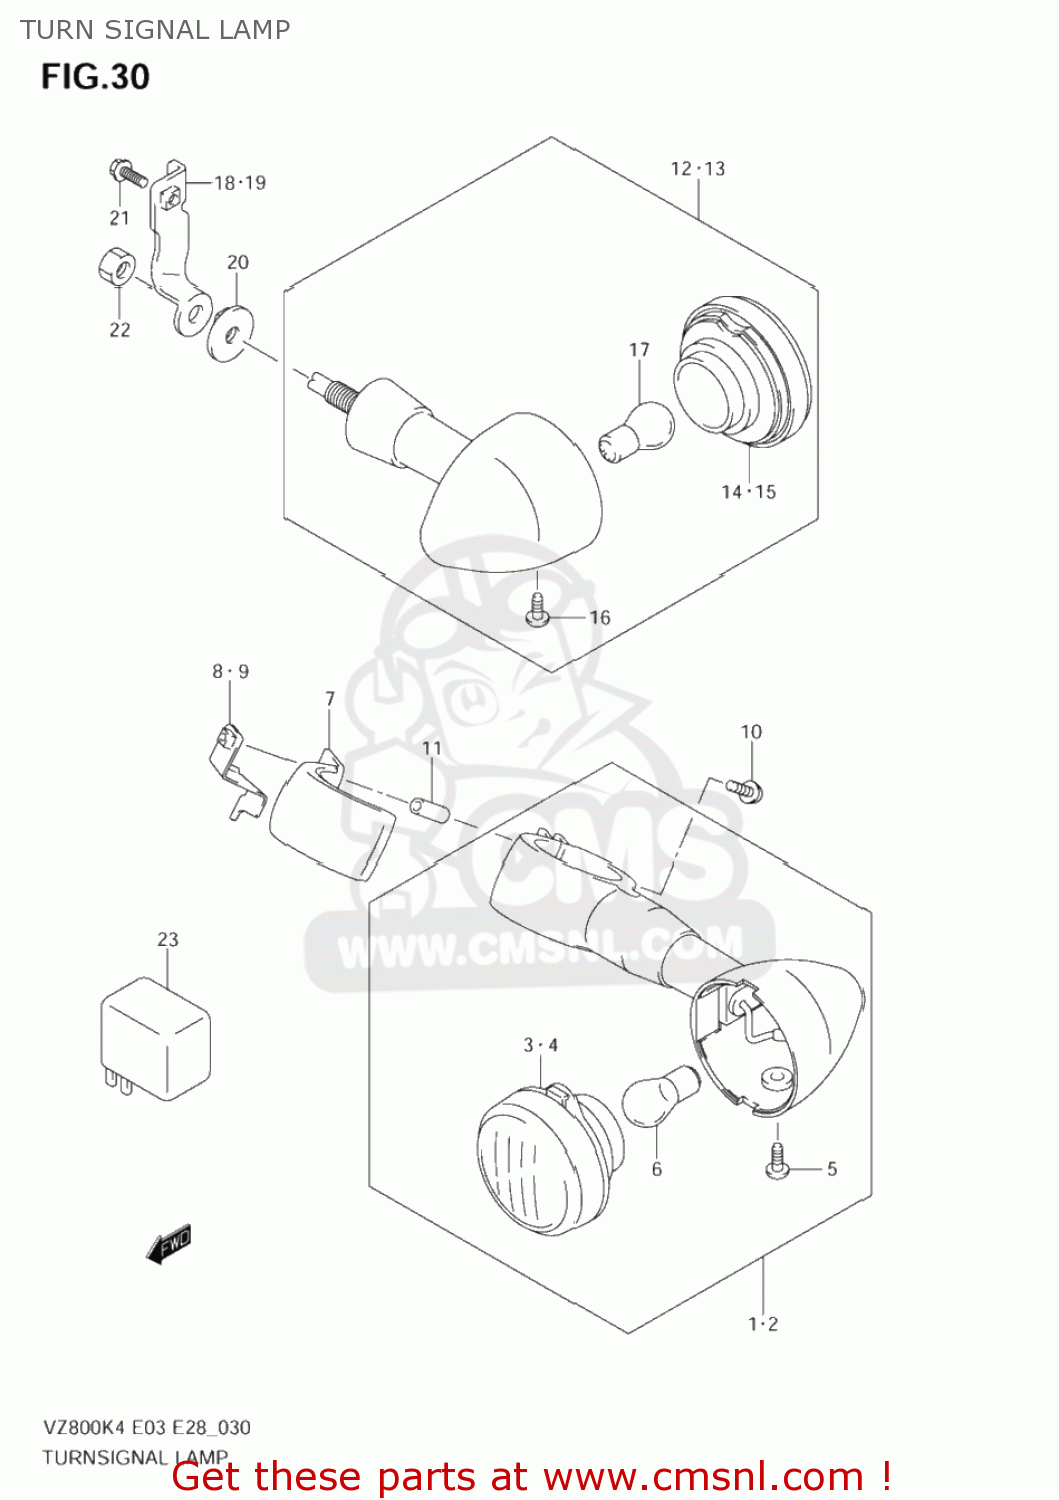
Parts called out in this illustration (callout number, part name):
1	LAMP ASSY,FR TURN SIGNAL,R
2	LAMP ASSY,FR TURN SIGNAL,L
3	LENS
4	LENS
5	SCREW(4X10)
6	BULB(12V21/5W)
7	COVER,FR TURNSIGNAL STAY
8	BRACKET,FR TURNSIGNAL,R
9	BRACKET,FR TURNSIGNAL,L
10	SCREW(6X25)
11	SPACER(6.4X9.2X12)
12	LAMP ASSY,RR TURNSIGNAL,R
13	LAMP ASSY,RR TURNSIGNAL,L
14	LENS
15	LENS
16	SCREW(4X10)
17	BULB(12V21W)
18	REINF,RR TURNSIGNAL,R
19	REINF,RR TURNSIGNAL,L
20	SPACER,RR TURNSIGNAL
21	BOLT
22	NUT
23	RELAY ASSY,TURNSIGNAL LAMP
